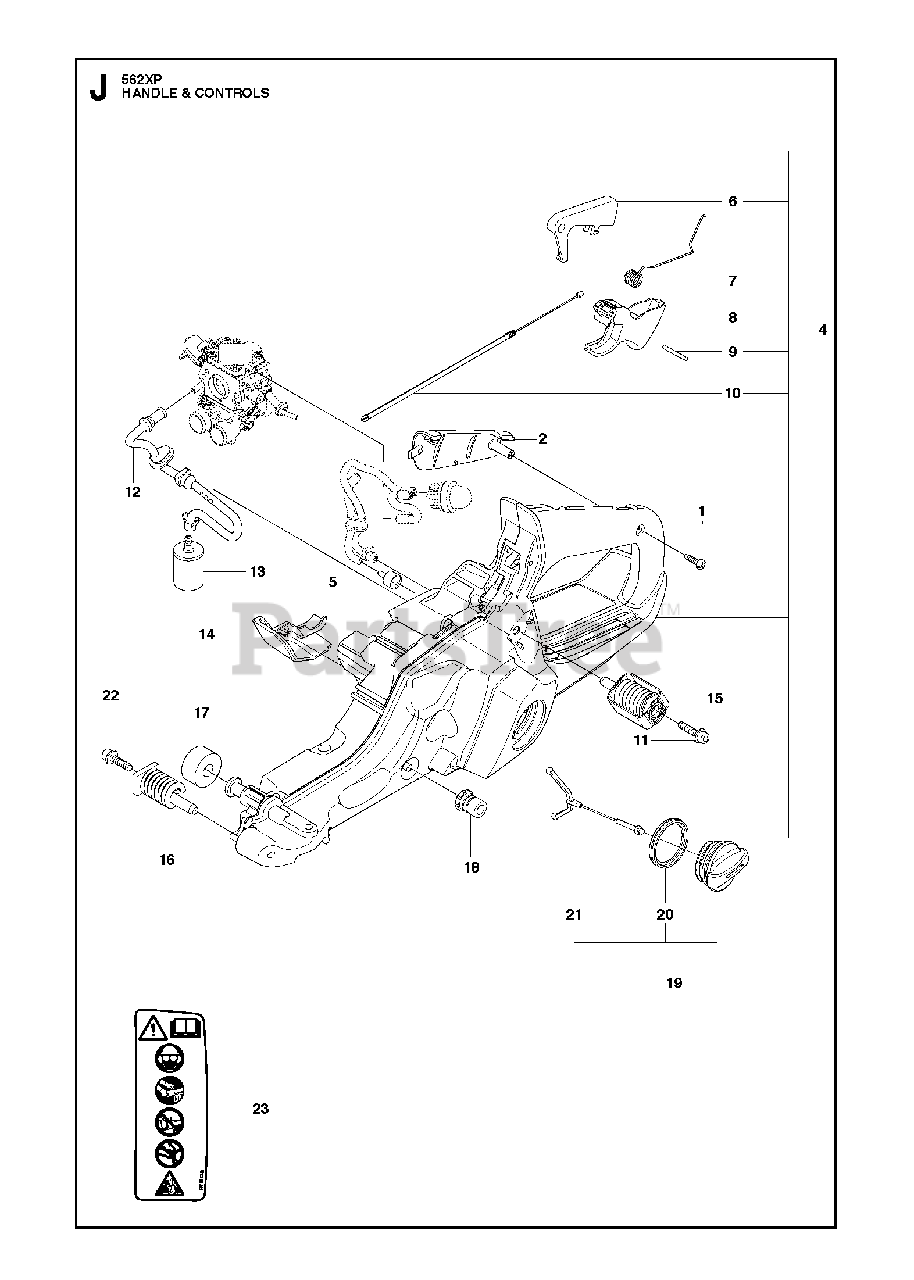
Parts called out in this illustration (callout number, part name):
2	HANDLE INSERT
4	FUEL TANK ASSY
5	FUEL TANK VENT
6	THROTTLE LOCKOUT
7	SPRING
8	THROTTLE
10	THROTTLE CABLE ASSY
13	FUEL FILTER
14	COVER
15	ANTIVIBRATION ELEMENT
16	ANITVIBRATION ELEMENT
17	DEFLECTION LIMITER
18	LATERAL SUPPORT
19	TANK CAP ASSY
20	SEALING
21	HOLDER
23	DECAL
